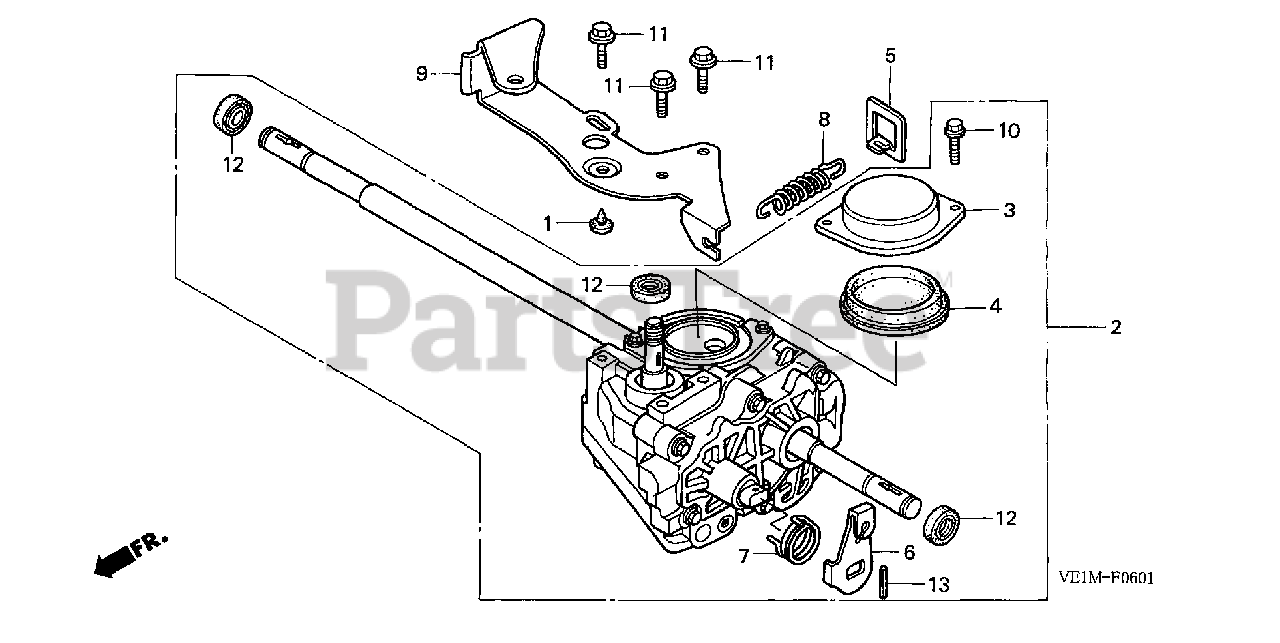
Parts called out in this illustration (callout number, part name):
1	RUBBER, TANK STOPPER
2	TRANSMISSION ASSY.
3	CAP, OIL
4	GASKET, OIL CAP
5	PLATE, TENSION SPRING
6	ARM, CONTROL
7	SPRING, CONTROL ARM RETURN
8	SPRING, WHEEL TENSION
9	HOLDER, WIRE
10	BOLT, FLANGE (5X12)
11	BOLT, FLANGE (6X16) (CT200)
12	OIL SEAL (13X22X5) (ARAI)
13	PIN, SPRING (4X25)
